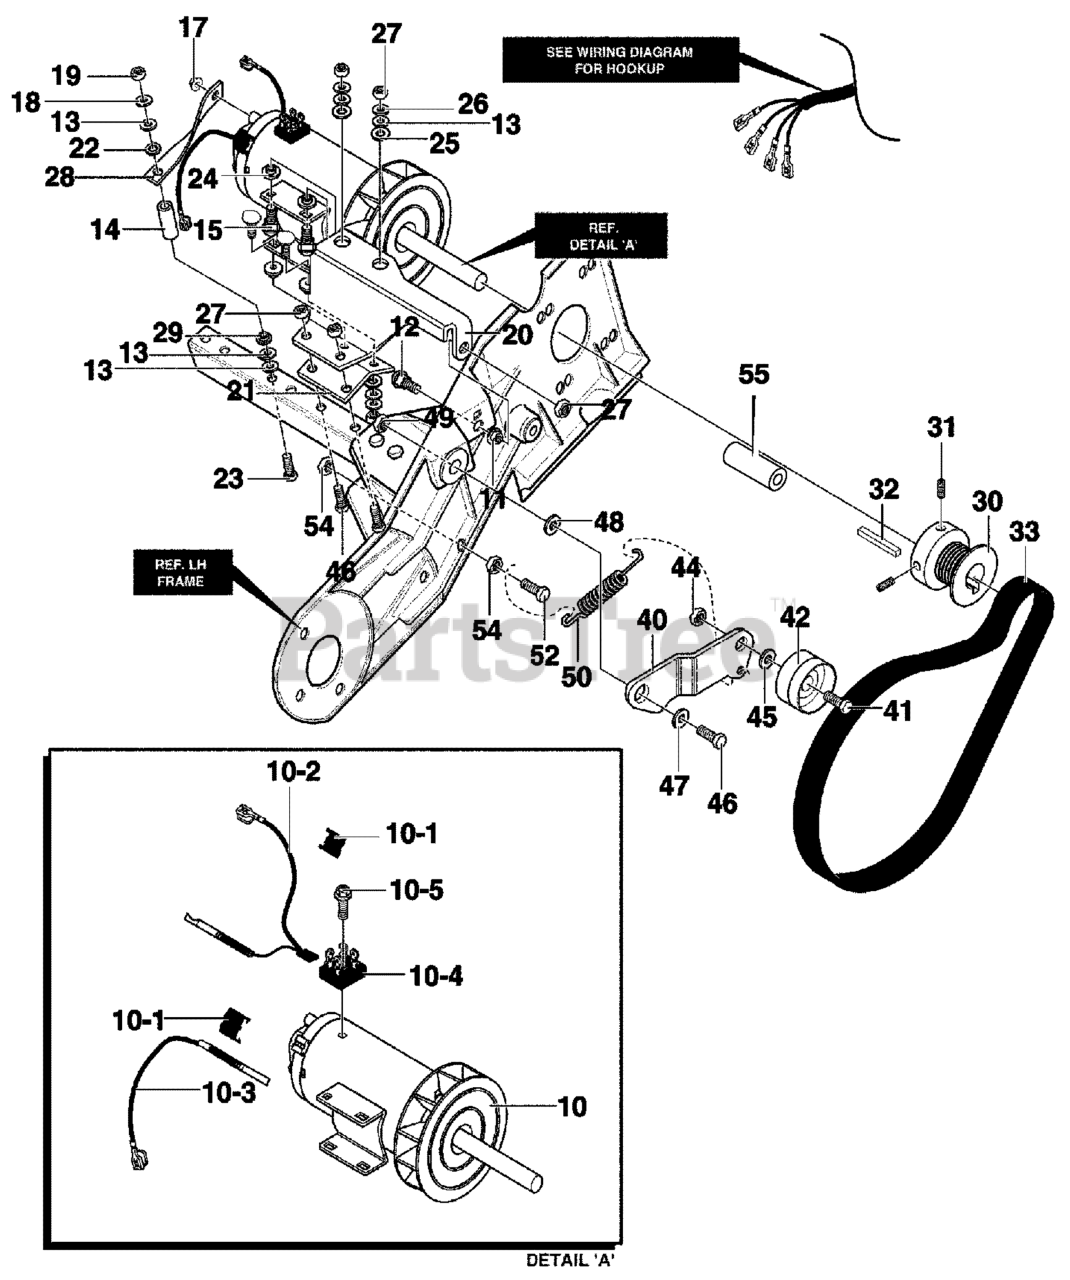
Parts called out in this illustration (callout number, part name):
10	MOTOR, ELECTRIC
10-1	BRUSH CAP
10-2	BRUSH CUT-OUT ASSEMBLY
10-3	BRUSH ASSEMBLY
10-4	RECTIFIER
10-5	SCREW, 10-24
11	NUT RETAINER
12	BOLT, 5/16-18 x .75
13	PLASTIC WASHER
14	TUBE, INSULATOR
15	BOLT, 5/16-18 x 1.00
17	NUT, #10-24
18	FLATWASHER
19	NUT, 1/4-20
20	BRACKET, UPPER MOTOR MOUNT
21	BRACKET, LOWER MOTOR MOUNT
22	FLATWASHER, NYLON
23	SCREW, 1/4-20 x 1.00
24	INSULATOR, MOTOR
25	INSULATOR WASHER
26	FLATWASHER
27	NUT, 5/16-18
28	BRACE, MOTOR
29	SHOULDER WASHER, NYLON
30	PULLEY, MOTOR
31	SCREW, 1/4-20 x .38
32	SQUARE KEY
40	IDLER BRACKET
41	SCREW, 3/8-16 x 1.50
42	IDLER PULLEY
44	NUT, 3/8-16
45	WASHER, Flat, 13/32
46	SCREW, 5/16-18 x 0.75
47	FLATWASHER
48	SPACER, SLEEVE
49	NUT, 5/16-18
50	IDLER SPRING -AUGER DRIVE
52	SCREW, 1/4-20 x 1.25
54	NUT. 1/4-20
55	INSULATOR, TUBE
